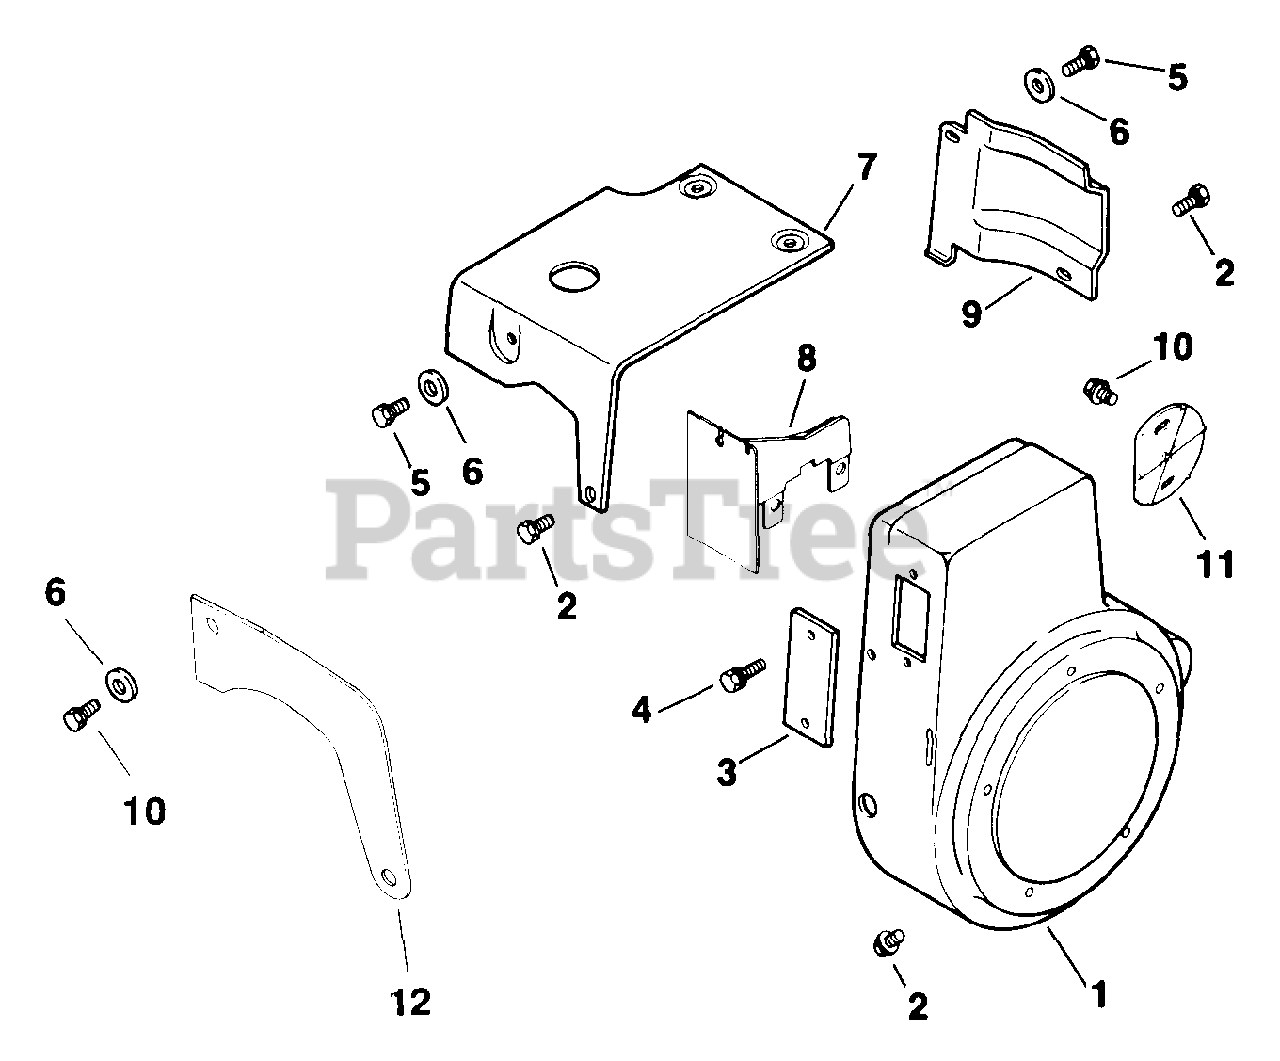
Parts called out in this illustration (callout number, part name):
1	KIT, HOUSING
2	SCREW, WSH HD TAP 1/4-20X7/16" USE 25 086 106-S
5	SCREW, SEMS 1/4-20X5/8" USE 25 086 539-S
6	WASHER, FLAT 1/4" (O.D. 5/8")
8	BAFFLE - DISCONTINUED
9	BAFFLE - DISCONTINUED
10	SCREW, POZ TRS HD 1/4-20X5/8" - DISCONTINUED
